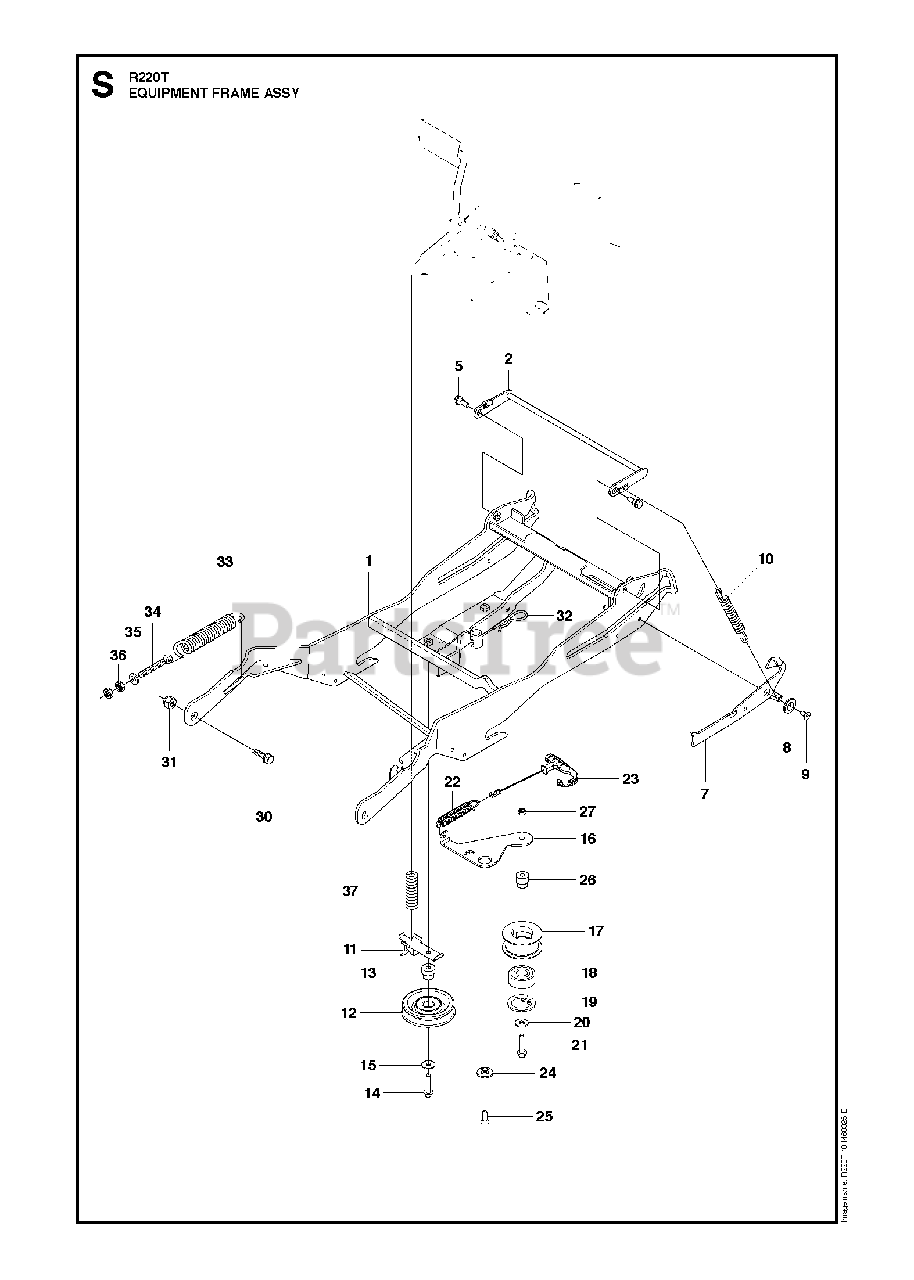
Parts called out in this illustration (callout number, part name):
1	EQUIPMENT FRAME
8	SPACER
9	SCREW IHCSFM
11	BRAKE
17	BELT TENSIONER WHEEL ASSY
18	BALL BEARING 6004-2RS1
19	RETAINING RING
23	HANDLE ASSY
24	WASHER
27	LOCKNUT M8
31	Lock Nut, Fiber M12 DIN 985 Z/P
35	WASHER
36	NUT
